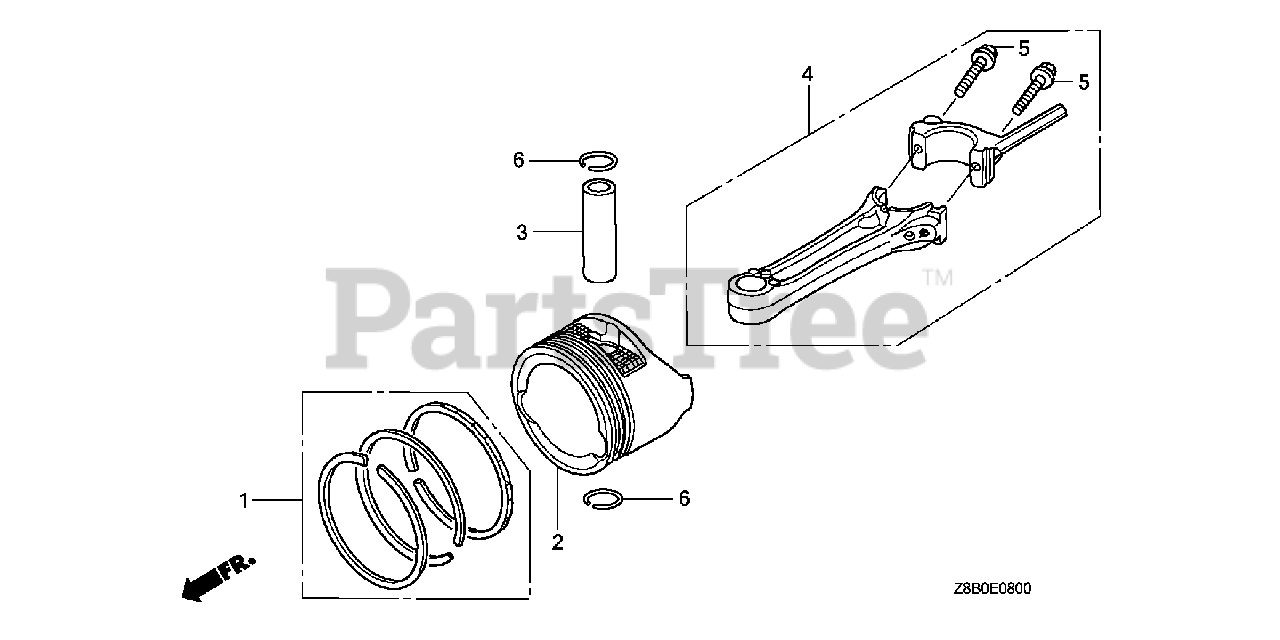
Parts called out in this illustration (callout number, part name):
1	RING SET, PISTON (STD) (TEIKOKU)
2	PISTON
3	PIN, PISTON
4	ROD ASSY., CONNECTING
5	BOLT, CONNECTING ROD
6	CLIP, PISTON PIN (13MM)
